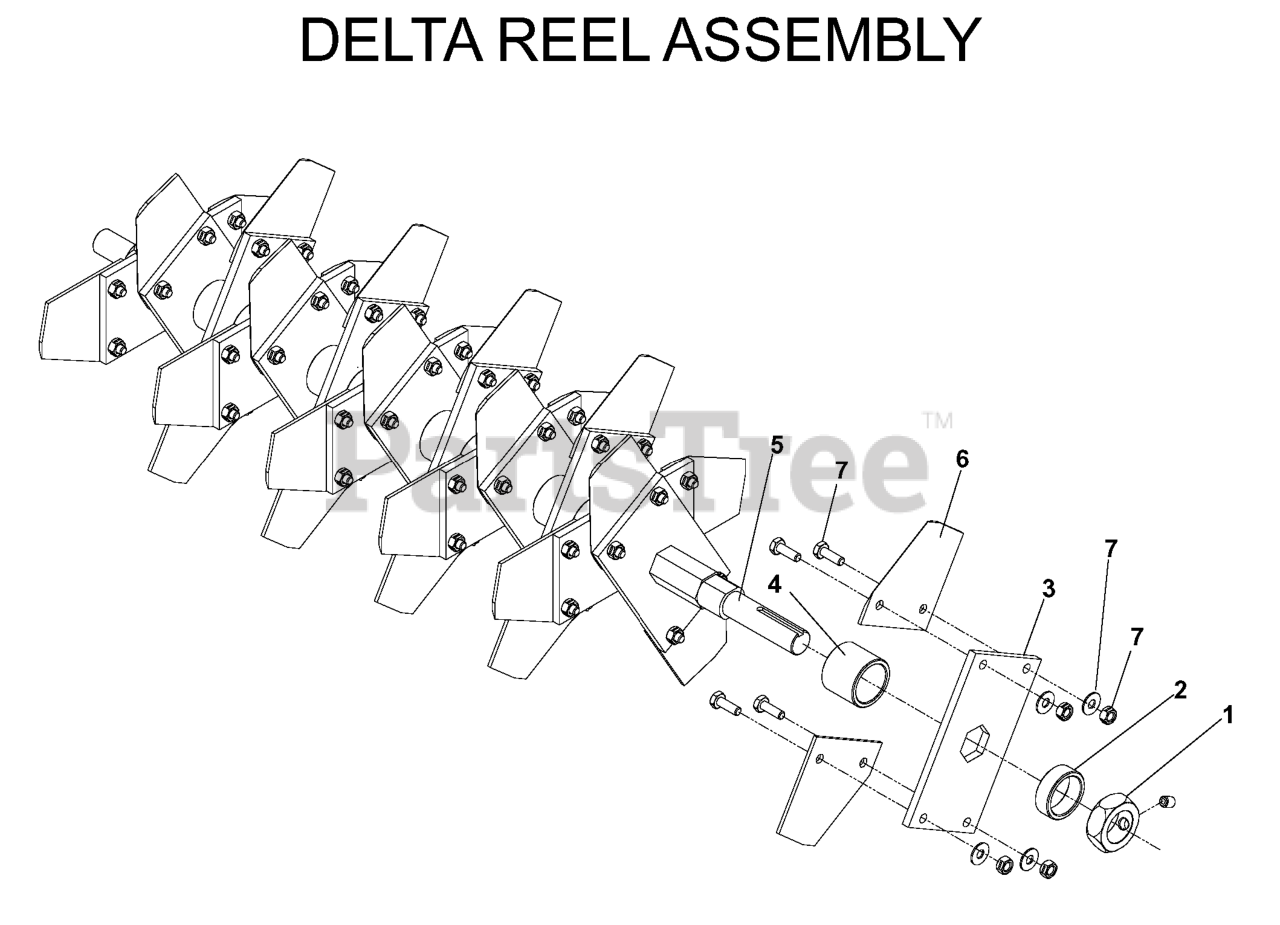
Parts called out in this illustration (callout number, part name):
1	JAM NUT W/SET SCREW
2	END SPACER
3	BLADE MOUNTING PLATE
4	SPACER - LONG
6	30 DELTA SET W/HARDWARE
7	SCREW & NUT (60 EACH)
539107184	22" DELTA REEL (COMPLETE)
